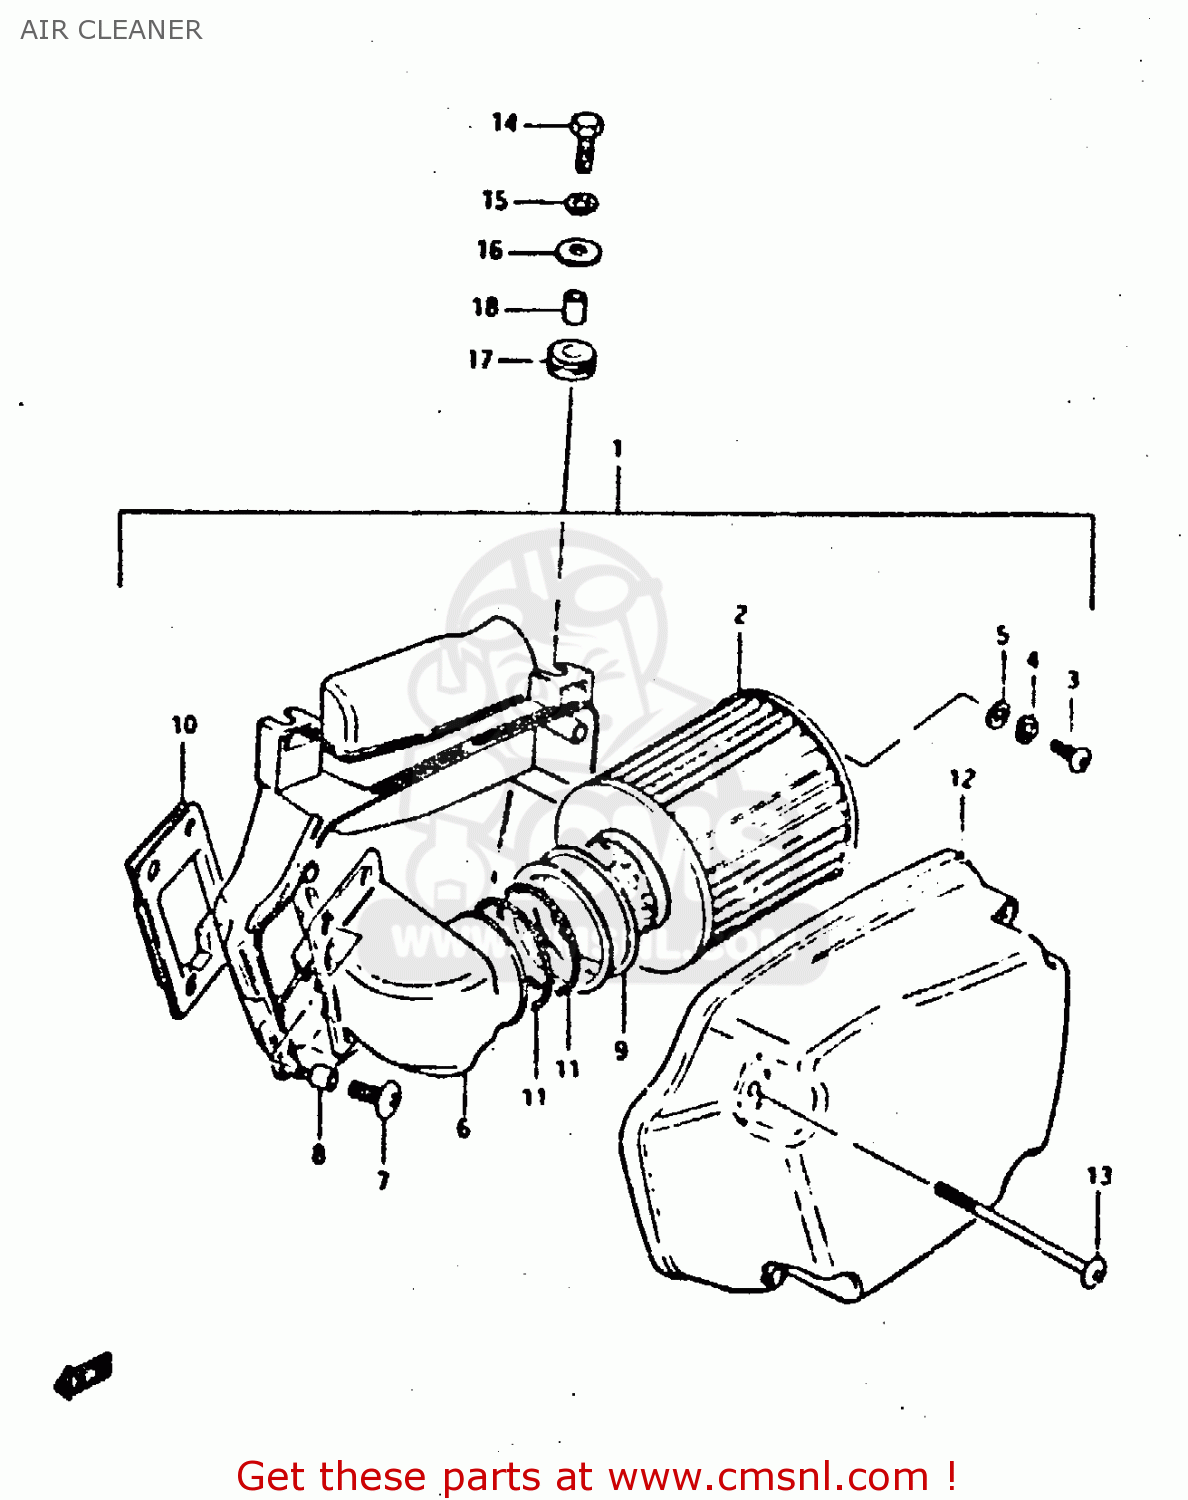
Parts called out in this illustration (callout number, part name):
1	CLEANER ASSEMBLY,AIR
2	FILTER
3	SCREW
4	LOCK WASHER
5	WASHER
6	TUBE,AIR CLEANER OUTLET
7	SCREW
8	COLLAR
9	JOINT
10	TUBE
11	SPRING,AIR CLEANER SIDE
12	CAP,AIR CLEANER
13	SCREW
14	BOLT 6X22
15	LOCK WASHER
16	WASHER
17	CUSHION
18	SPACER(6.1X9X7.5)
